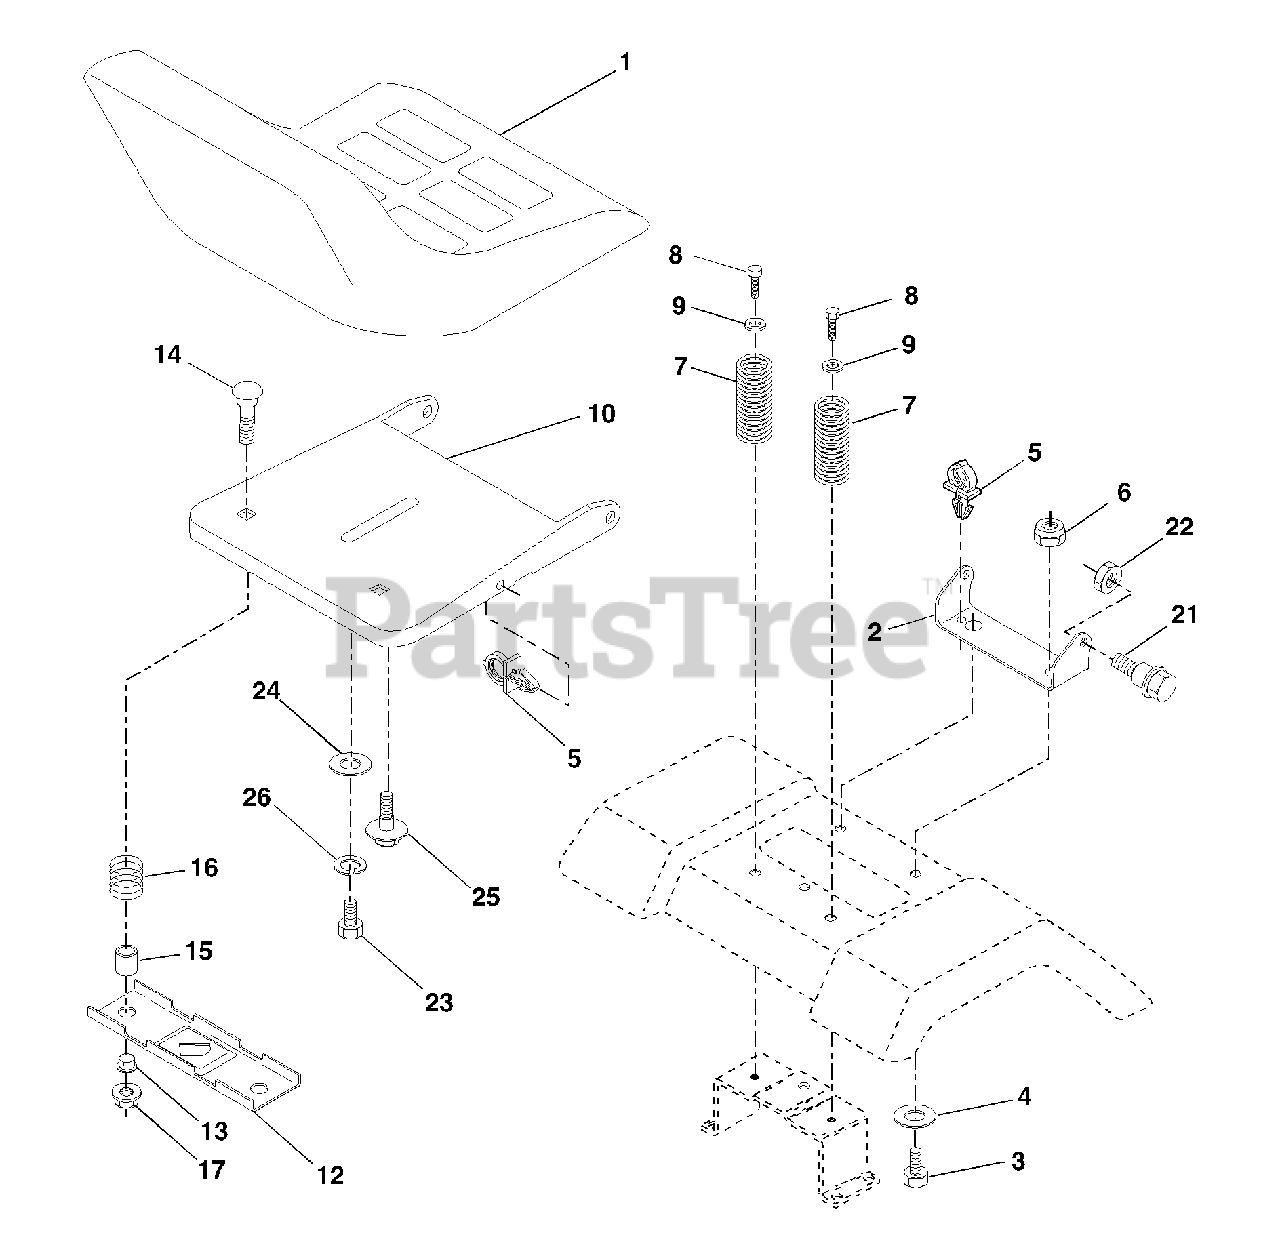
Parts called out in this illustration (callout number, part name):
1	Seat
2	Bracket Seat Pivot
3	Bolt Hex 3/8 - 16 X 1
4	Washer 13/32 X 1 X10Ga.
5	Clip Push-In Hinged
6	Nut Lock Hex w/Ins 3/8 - 16
7	Spring Seat Cprsn 2 250 Blk Zi
8	Screw 3/8-16 x 1.5
9	Washer 13/32 X 1 X 14 Ga
10	Pan Pnt Seat (Blk)
12	Bracket Pnt Mounting Switch
13	Bushing Snap Blk Nyl
14	Bolt Rdhd Sht Nk 1/4 - 20 X 1 -1/2
15	Spacer Split .28 X .96
16	Spring Cprsn
17	Nut Lock 1/4 Lge Flg
21	Bolt Shoulder 5/16-18 Unc-2A
22	Nut Lock Hex w/Ins 5/16 - 18
23	Bolt Hex Black
24	Washer 17/32 X 1-3/16 X 12 Ga
25	Bolt Shoulder 5/16-18 X .62
26	Washer Lock Hvy Hlcl Spr 1/2
